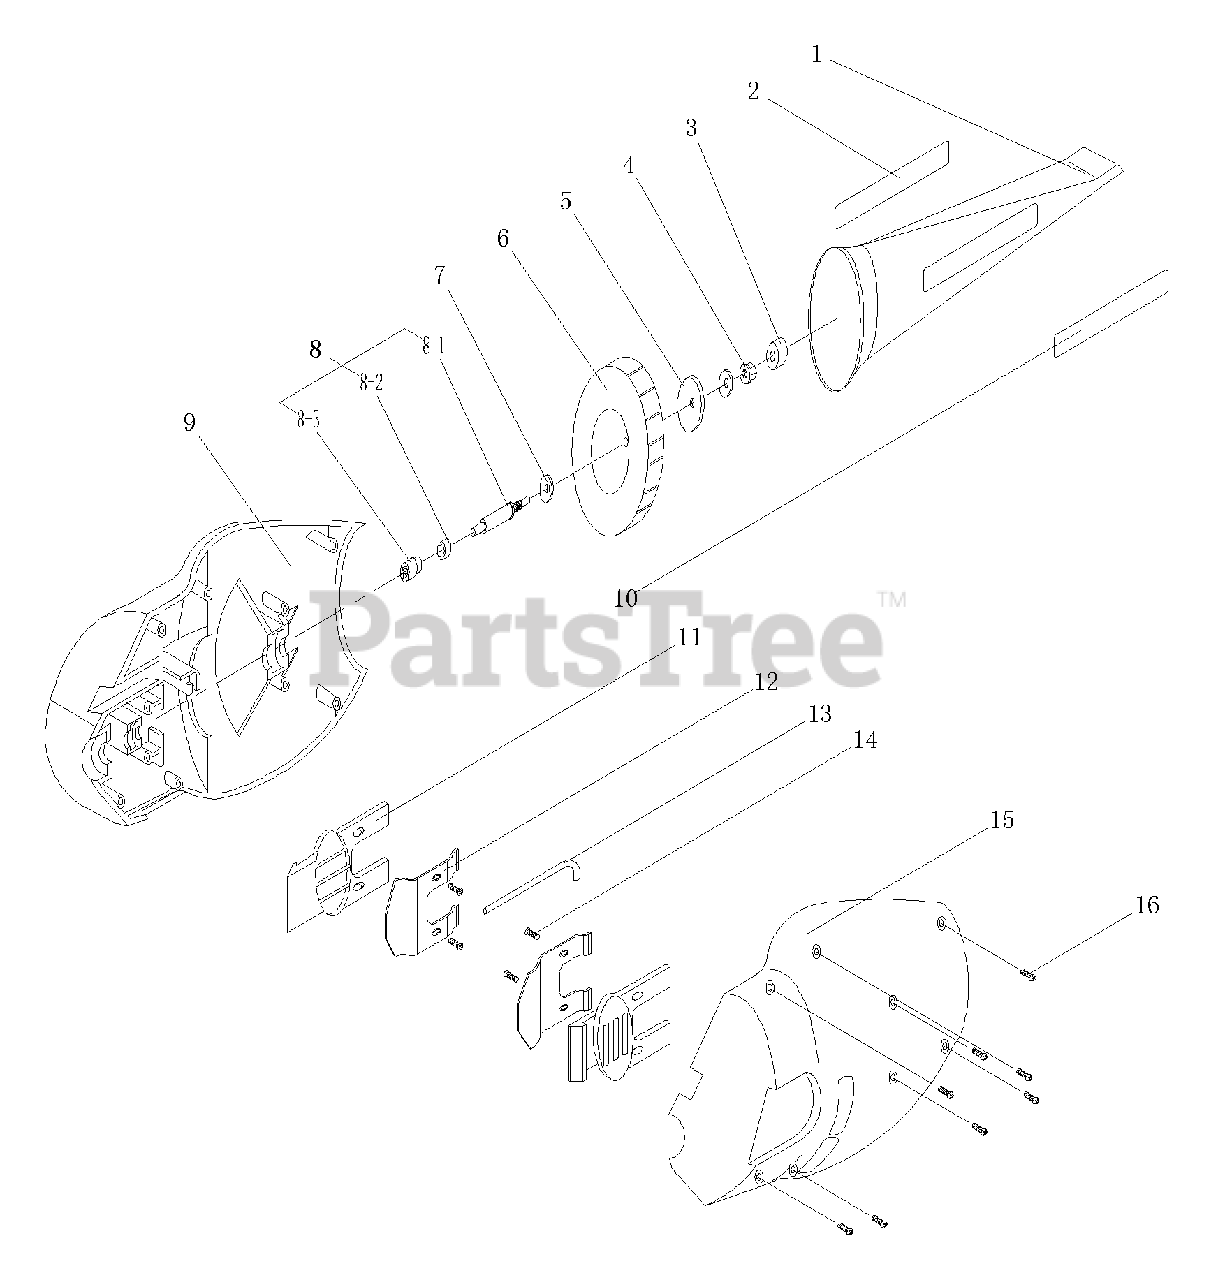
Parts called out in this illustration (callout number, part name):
8	PIVOT ASS'Y
9	CONNECT (L)
12	SPRING LAMINATION
15	CONNECT (R)
